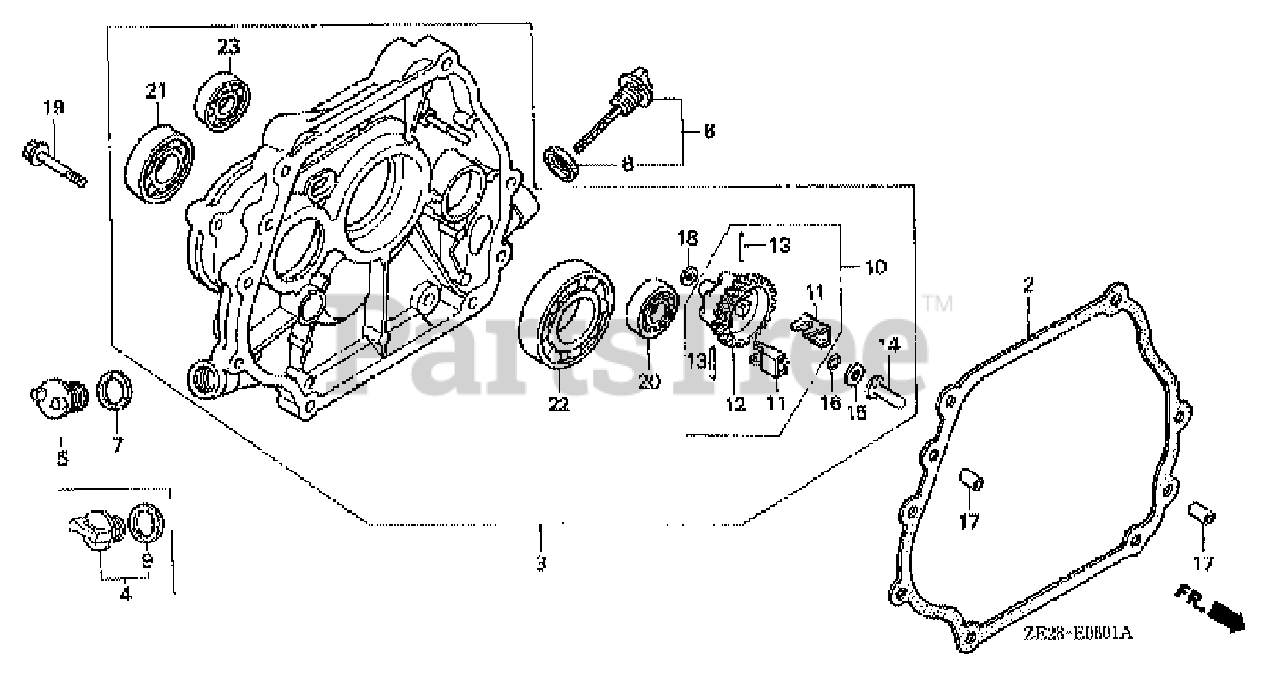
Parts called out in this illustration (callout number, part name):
2	GASKET, CASE COVER
3	COVER ASSY., CRANKCASE (H-TYPE)(BALANCER)
4	CAP ASSY., OIL FILLER
5	CAP, OIL FILLER
6	CAP ASSY., OIL FILLER
7	GASKET, OIL FILLER CAP
8	GASKET, OIL FILLER CAP
9	GASKET, OIL FILLER CAP
10	GOVERNOR ASSY. (BALANCER)
11	WEIGHT, GOVERNOR
12	HOLDER, GOVERNOR WEIGHT
13	PIN, GOVERNOR WEIGHT
14	SLIDER, GOVERNOR
15	WASHER (6X16)
16	CLIP, GOVERNOR HOLDER
17	PIN, DOWEL (8X12)
18	WASHER, PLAIN (6MM)
19	BOLT, FLANGE (8X35)
20	BEARING, RADIAL BALL (6202)
21	BEARING, RADIAL BALL (6204)
22	BEARING, RADIAL BALL (6206)
23	BEARING, RADIAL BALL (6302)
